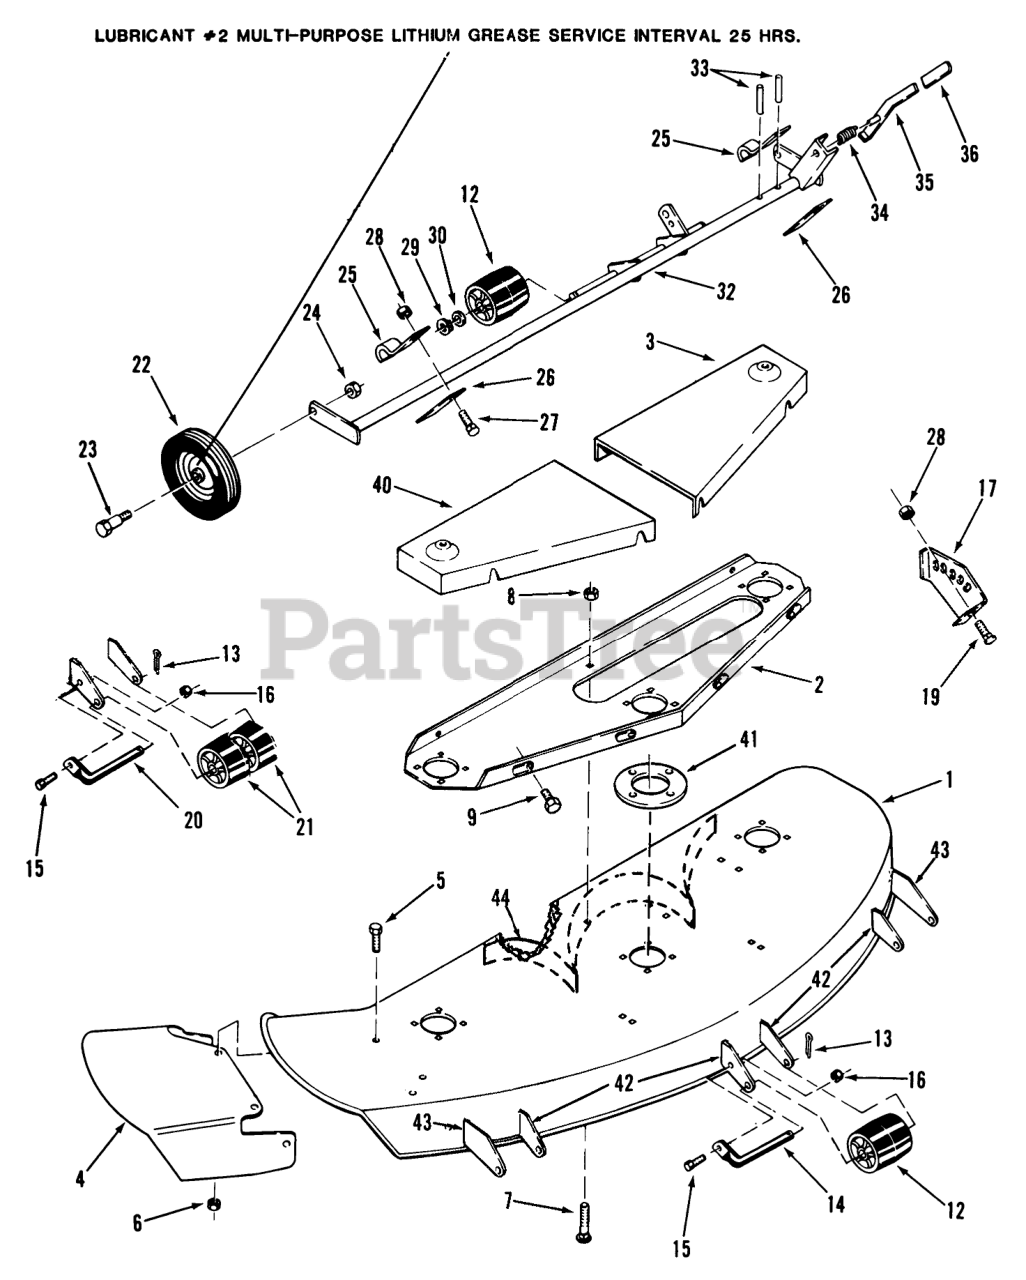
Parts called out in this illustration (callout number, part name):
1	ASSY DECK 42"MOWE R
1	ASSY-48 MOWER DEC R
1	Mower Deck-48 in.
2	Channel
3	Belt Cover LH
4	Chute Extension
4	GUARD WA - 48" CHUTE R (NS)
5	Bolt
6	Nut
7	Bolt-Carriage
8	NUT
9	SCREW -4
9	Screw
12	Roller
13	Cotter Pin
14	ROLLER-SHAFT
15	Bolt 1/4-20 x 3/4
16	Nut
17	Quadrant
17	LH QUADRANT R
19	Bolt-Carriage
19	Bolt
20	SHAFT-ROLLER
21	ROLLER
22	WHEEL
22	WHEEL 6" X 1.75
22	WHEEL-GAUGE HD
23	BOLT-SHOULDER
23	BOLT SHOULDER
24	Nut
25	Clamp
26	Bar
27	Bolt
28	NUT
29	Retaining Ring
30	Washer
32	ASSY GAGE WHEEL S R (NS)
32	ASSY-GAGE WHEEL S R
32	Gage Wheel Support
33	PIN-SPIROL
34	SPRING-COMPRESSION
35	LEVER ASSY R
35	Lever
40	Belt Cover RH
41	PLATE-SPINDLE
42	SUPPORT-ROLLER SH R
43	SUPPORT-ROLLER LONG
44	Baffle
